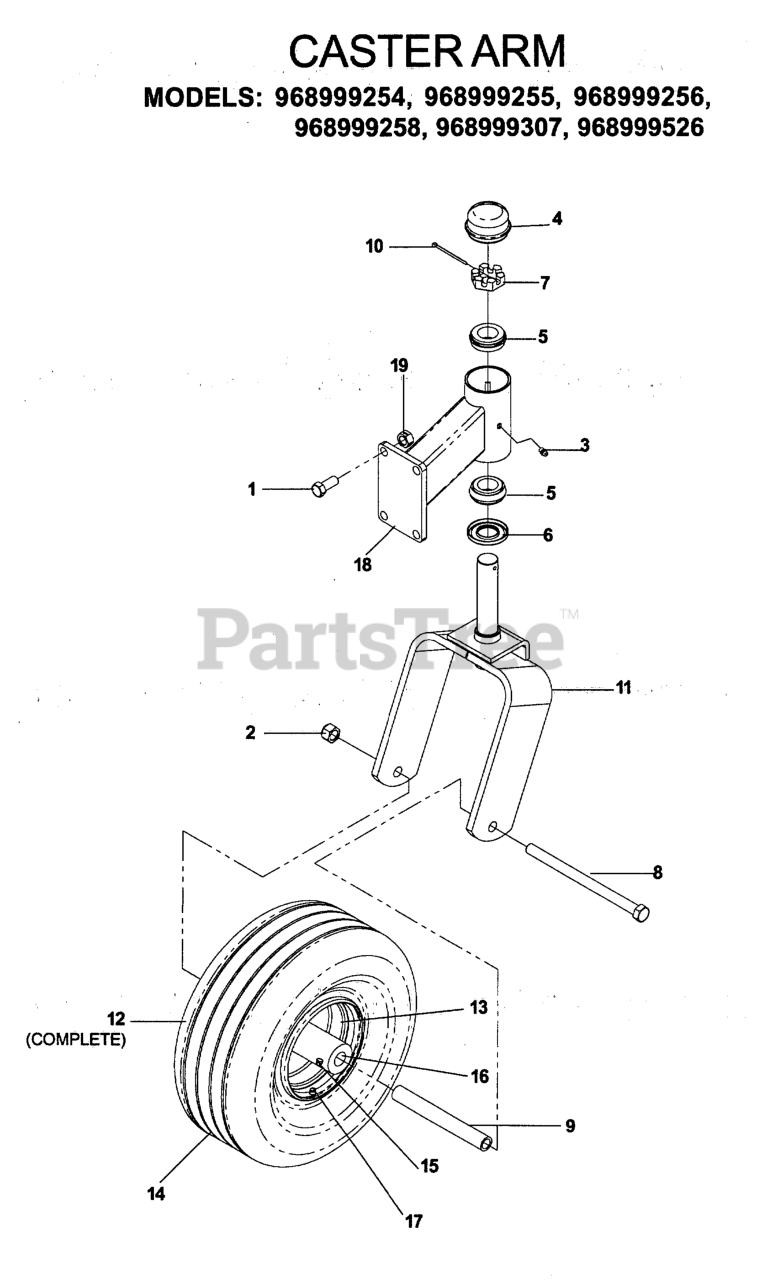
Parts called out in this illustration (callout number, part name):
1	HCS 7/16-14 X 1 GR 5 ZD
2	NUT 1/2-13 HEX NYLOC ZD
4	GREASE CAP
5	TAPERED ROLLER BRG
7	NUT 1"C HEX SLOTTED
8	SCREW 1/2C X 7 1/2 HEX CAP
9	SPACER, CASTER
10	COTTER PIN 1/8 X 2
11	CASTER YOKE ORANGE
12	TIRE.ASSEM.13X5-6.SMOOTH.SILVE
13	RIM
14	TIRE - FRONT
15	ZERK 1/8 NPT
16	BEARING RETAINER
17	VALVE STEM TR-412
18	CASTER ARM, ORG
19	NUT 7/16C CENTERLOCK
